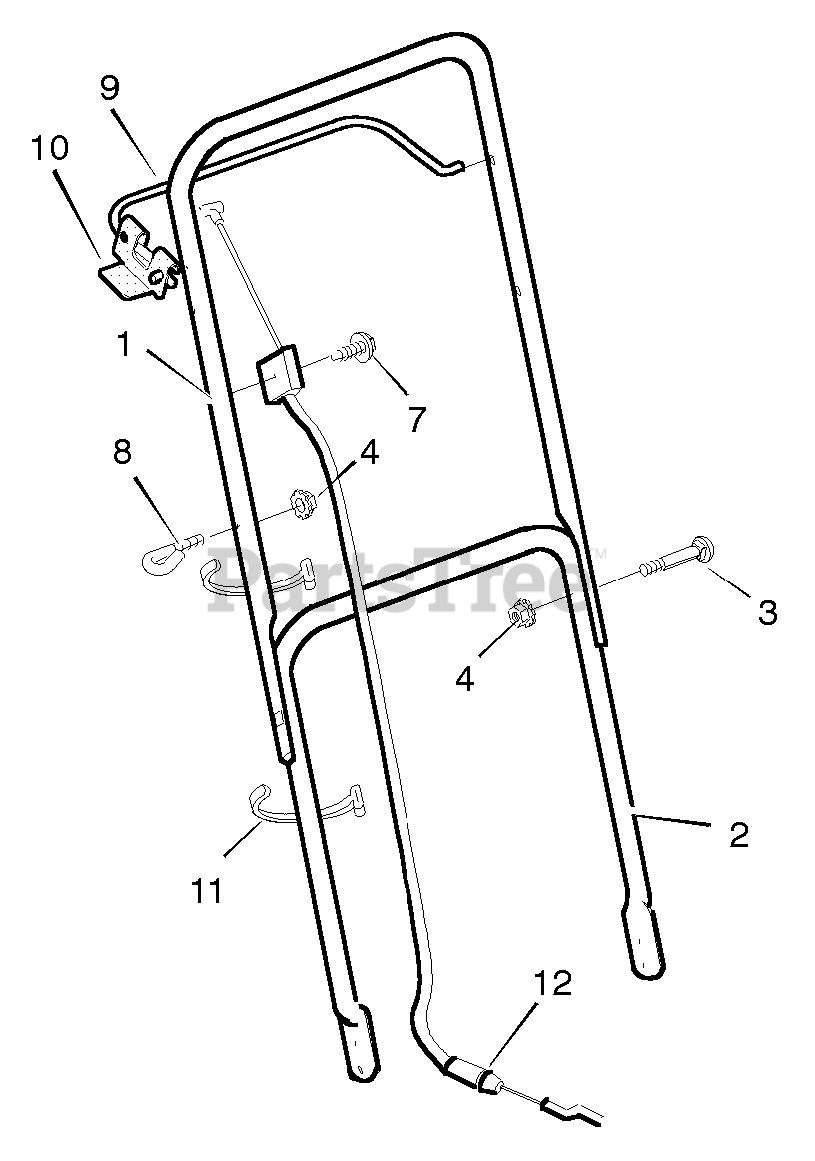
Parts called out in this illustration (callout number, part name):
1	Handle, Upper - Straight
2	Handle, Lower
4	Locknut
8	GUIDE, ROPE
9	Engine Stop Lever - Straight
10	Bracket, Stop Lever
11	Fastener, Cable
12	Engine Stop Cable
